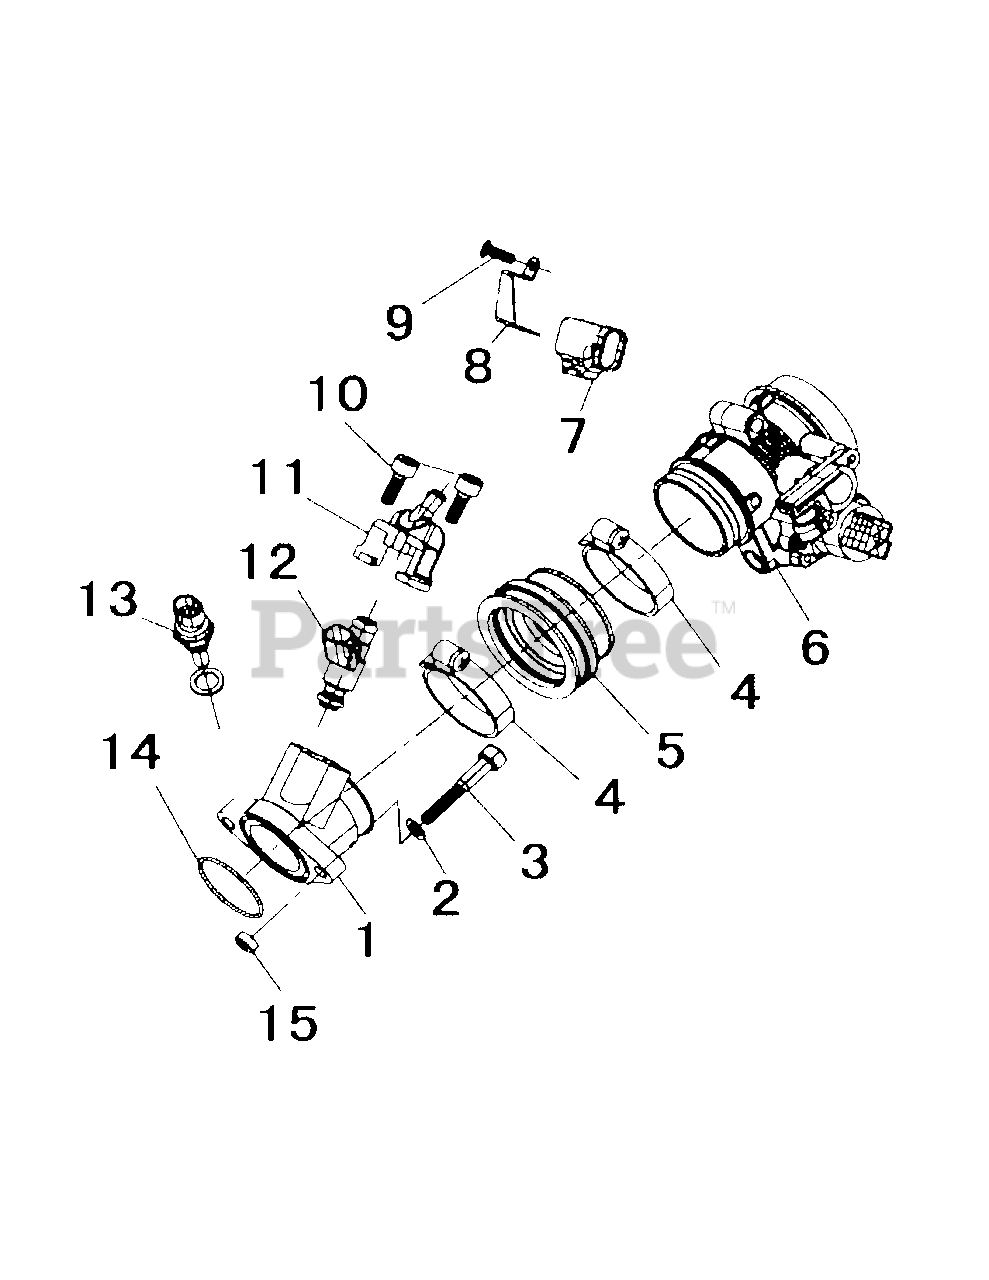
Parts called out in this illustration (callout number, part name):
3	Screw-Hex Head M8 X 50
5	Joint Inlet Pipe
6	Throttle Asm-D46-5
7	Pressure Sensor-Intake 28086011
8	Press Plate-Tmap
10	Screw-Cylinder M6 X 20 Inner
11	Seat-Fuel Injection
12	Fuel Injector-28160355
13	Sensor-Water Temperature
15	Bush-Inlet Pipe
